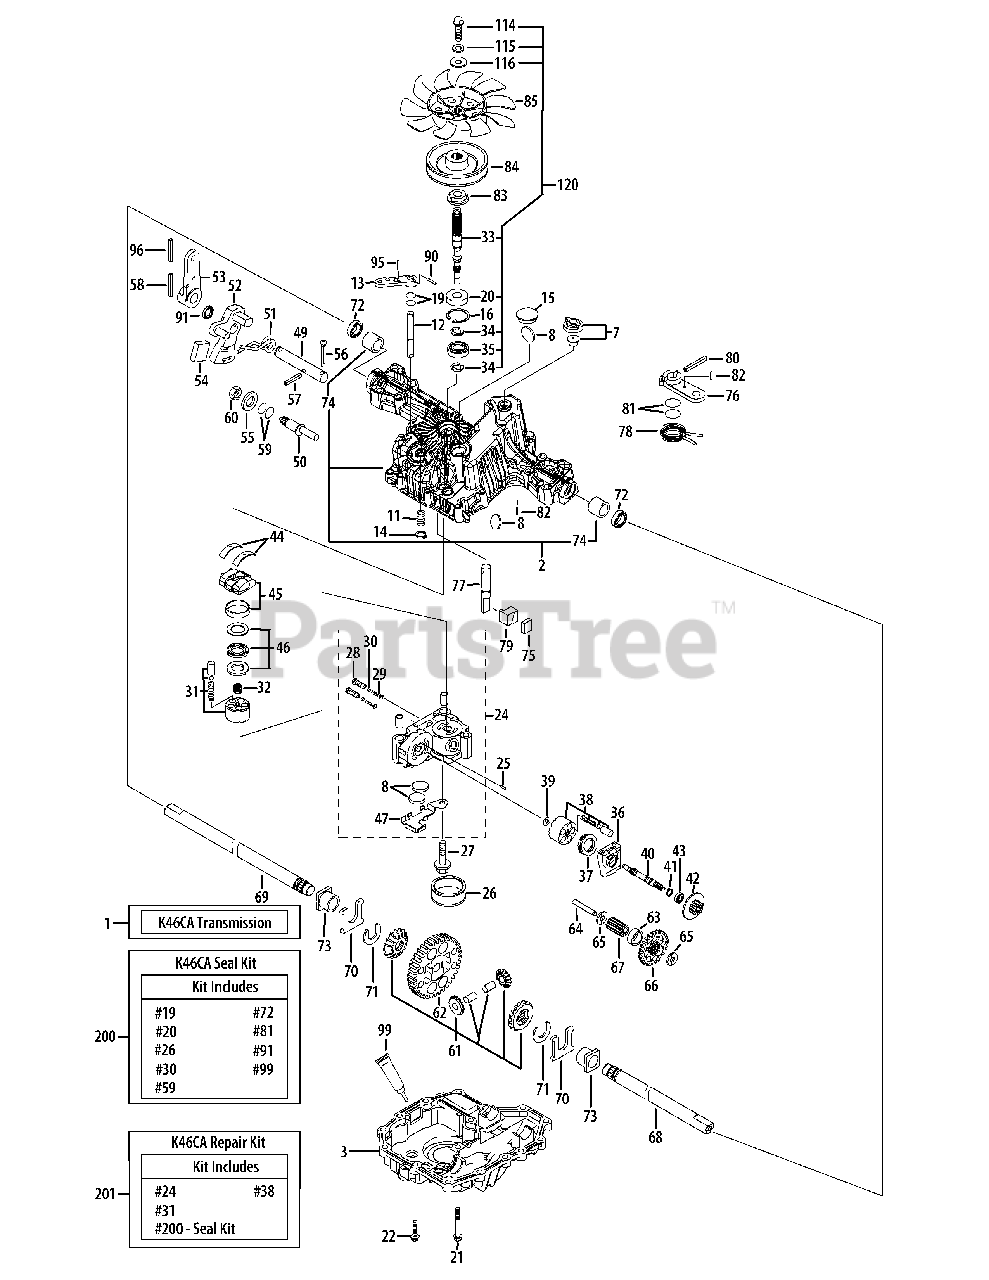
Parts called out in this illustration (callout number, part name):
1	K46CA Transaxle
2	Kit, Upper Case
3	Lower Case
7	Vent Valve 15
12	Bypass Shaft A
14	Snap Ring 10
15	Sealing Cap 30
16	Snap Ring C 35
19	O-Ring 1A P10A
20	Seal TC 153507
21	Tapping Screw 8 x 55
22	Tapping Screw 8 x 30
24	Kit, Center Case C
26	Filter 105
28	IDS Valve 1.2
30	IDS Filter 300
31	Kit, Cylinder Block (Pump)
34	E-Ring 15
35	Bearing 6202C3
36	Motor Housing
37	Thrust Bearing 51106
38	Kit, Cylinder Block
39	Washer 12 x 24 x 1
41	Snap Ring C15
42	Brake Disc/Motor Gear (11T)
43	Bearing 6202 RSR C3
44	Thrust, Plastic
45	Swash Plate Assembly
46	Kit, Thrust Bearing (Pump)
47	Magnet Holder
49	Control Shaft
51	Torsion Spring, Standard
52	Control Arm A
53	Control Lever F
56	Cotter Pin 1/8" x 3/4"
57	Spring Pin 6 x 36
58	Roll Pin 6 x 40
61	Diff Gear Kit
62	Final Gear (54T)
63	Final Pinion Collar
64	Reduction Shaft
65	Washer 12 x 32 x 3.2
66	Reduction Gear (37T)
67	Final Pinion Gear (10T)
68	Axle Shaft, Left
69	Axle Shaft, Right
70	Thrust Washer
72	Seal 19 x 32 x 8
73	Bushing 19 x 25
74	Bushing 19.05
78	Brake Return Spring
79	Brake Actuator
80	Spring Pin 5 x 32
81	O-Ring 1A P12
82	Spring Pin 4 x 16
83	Spline Collar
90	Spring Pin 3.0A x 20
91	Oil Seal 16 x 22 x 03
95	Spring Pin 3.0A x 16
96	Roll Pin 3.5 x 40
99	Sealant
120	Pump Shaft/Bearing Kit
200	Kit,Seal
201	Repair Kit
